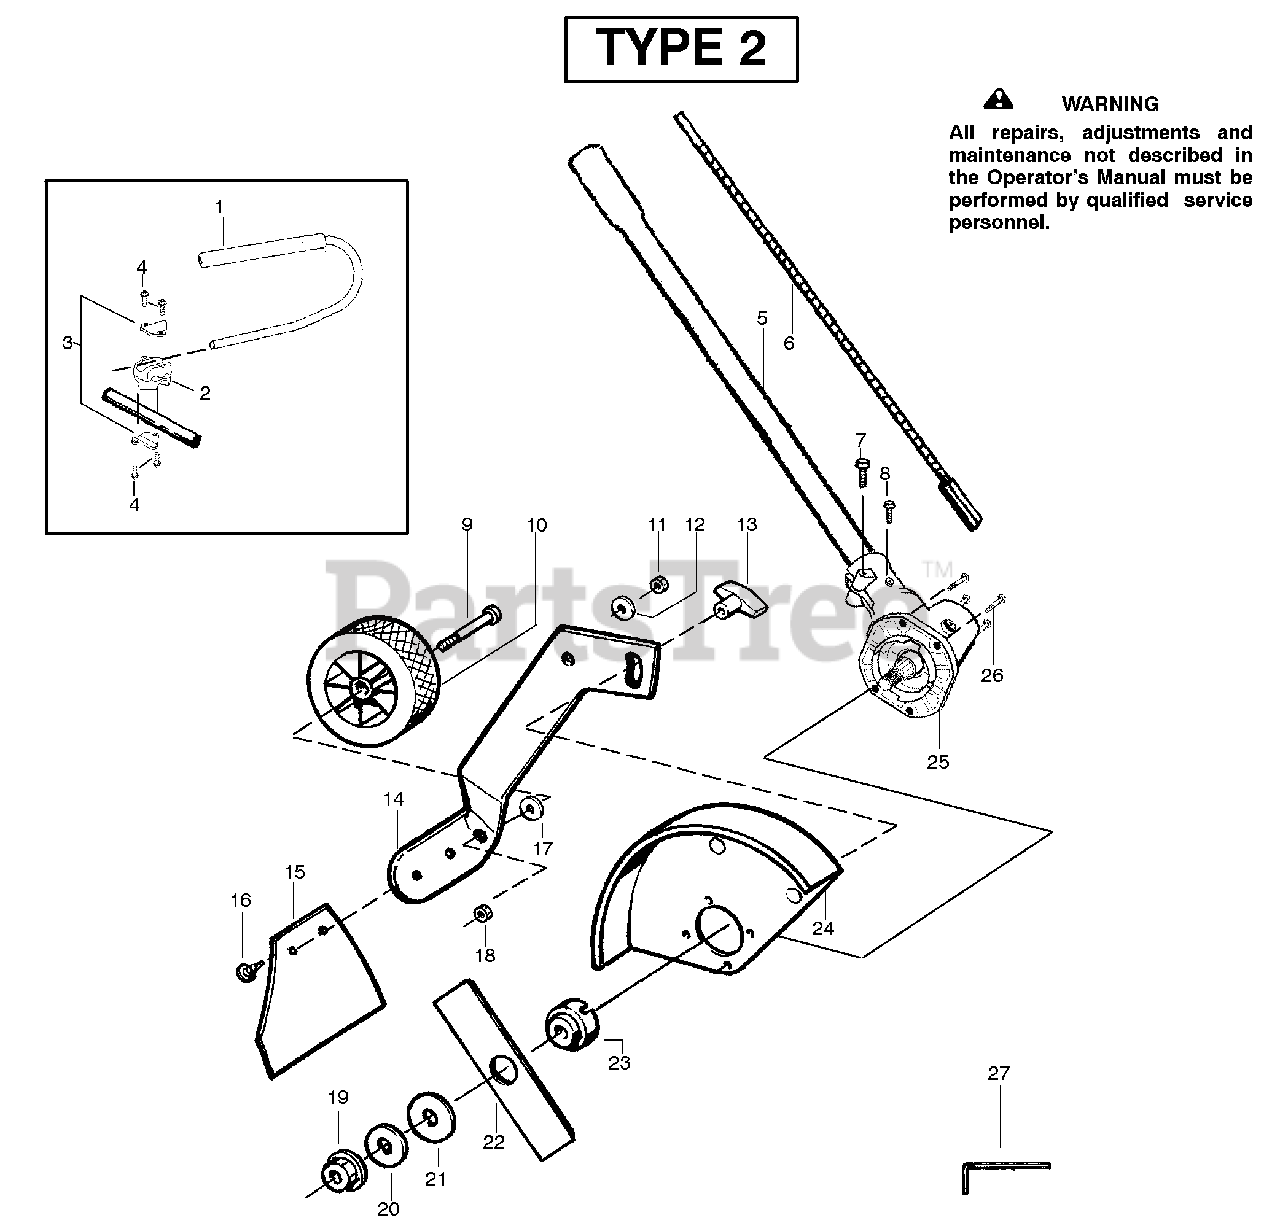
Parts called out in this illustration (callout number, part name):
1	Kit - Handlebar
2	Clamp - Handlebar
3	Bracket - Clamp
5	Assy. - Driveshaft
6	Flexshaft - Split boom
8	Screw - Alignment
9	Bolt - Shoulder Axle
10	Wheel - 4"
14	Bracket - Adj. Wheel
15	Kit - Mud Flap
16	Fastener - Mud Flap
19	Nut - Flange
20	Washer - Belleville
21	Washer - Flat
22	7.5" Blade
24	Kit - Edger Guard
25	Kit - Gearbox
27	Wrench - Hex
